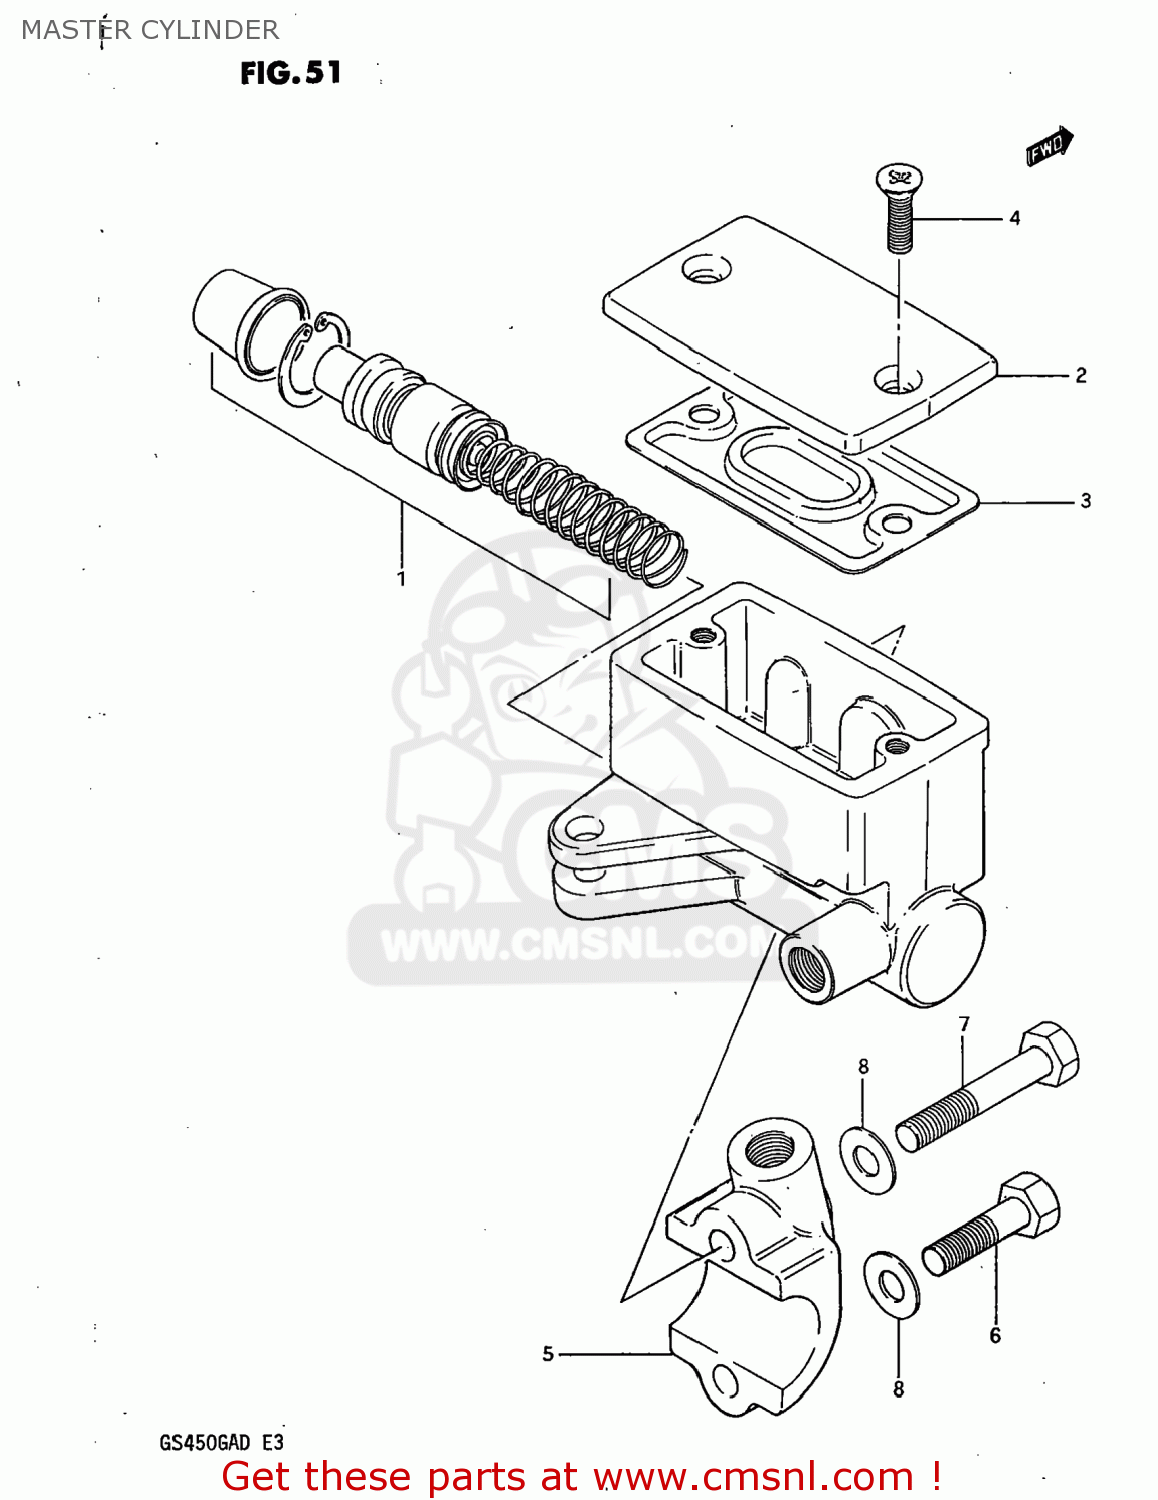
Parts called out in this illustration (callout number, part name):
1	PISTON & CUP SET
2	CAP
3	4
4	SCREW
5	HOLDER
6	BOLT
7	BOLT 6X40
8	WASHER
